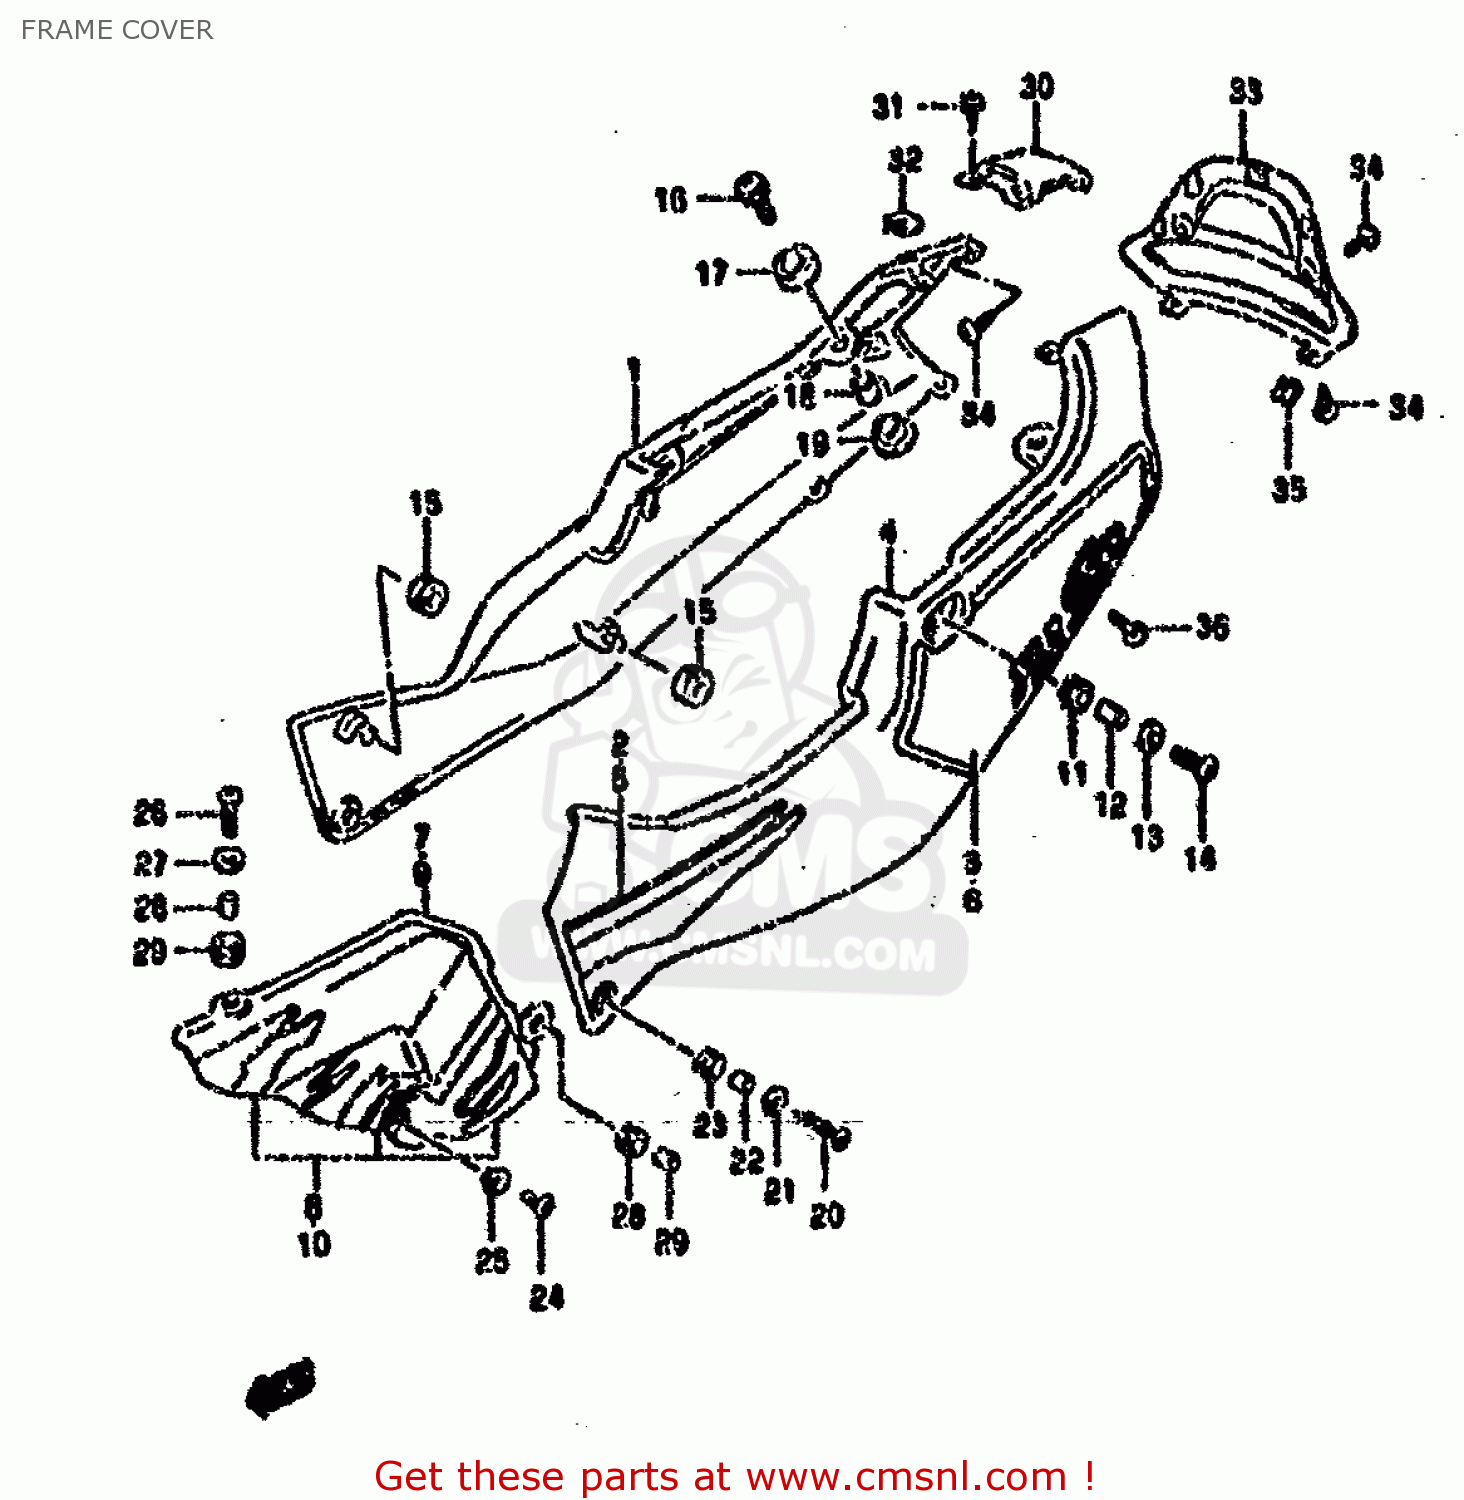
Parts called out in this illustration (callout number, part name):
1	COVER ASSY,FRAME RH (WHITE)
2	TAPE,FRAME COVER STRIPE,R
3	TAPE,ZECKEN RH (BLACK)
4	COVER ASSY,FRAME LH (WHITE)
5	TAPE,FRAME COVER STRIPE,L
6	TAPE,FRAME COVER STICKER ,LH
7	COVER ASSY,FRAME BODY,R
8	TAPE SET,FRAME COVER B
9	COVER ASSY,FRAME BODY,L
10	TAPE SET,FRAME COVER B
11	CUSHION
12	SPACER (6.3X9.1X6.7)
13	WASHER(6.5X22X1.6)
14	SCREW(6X20)
15	CUSHION
16	SCREW(6X30)
17	CUSHION,TAIL COVER UPR
18	SPACER (6,8X10X9.4)
19	CUSHION,FRAME COVER LWR
20	SCREW(6X30)
21	WASHER
22	SPACER (6.1X9X9)
23	CUSHION
24	SCREW(5X14)
25	WASHER
26	SCREW
27	WASHER
28	SPACER (6.1X9X9)
29	CUSHION
30	COVER ASSY,FRAME CTR
31	SCREW
32	NUT
33	COVER,FRAME RR
34	SCREW(5X12)
35	NUT
36	SCREW
